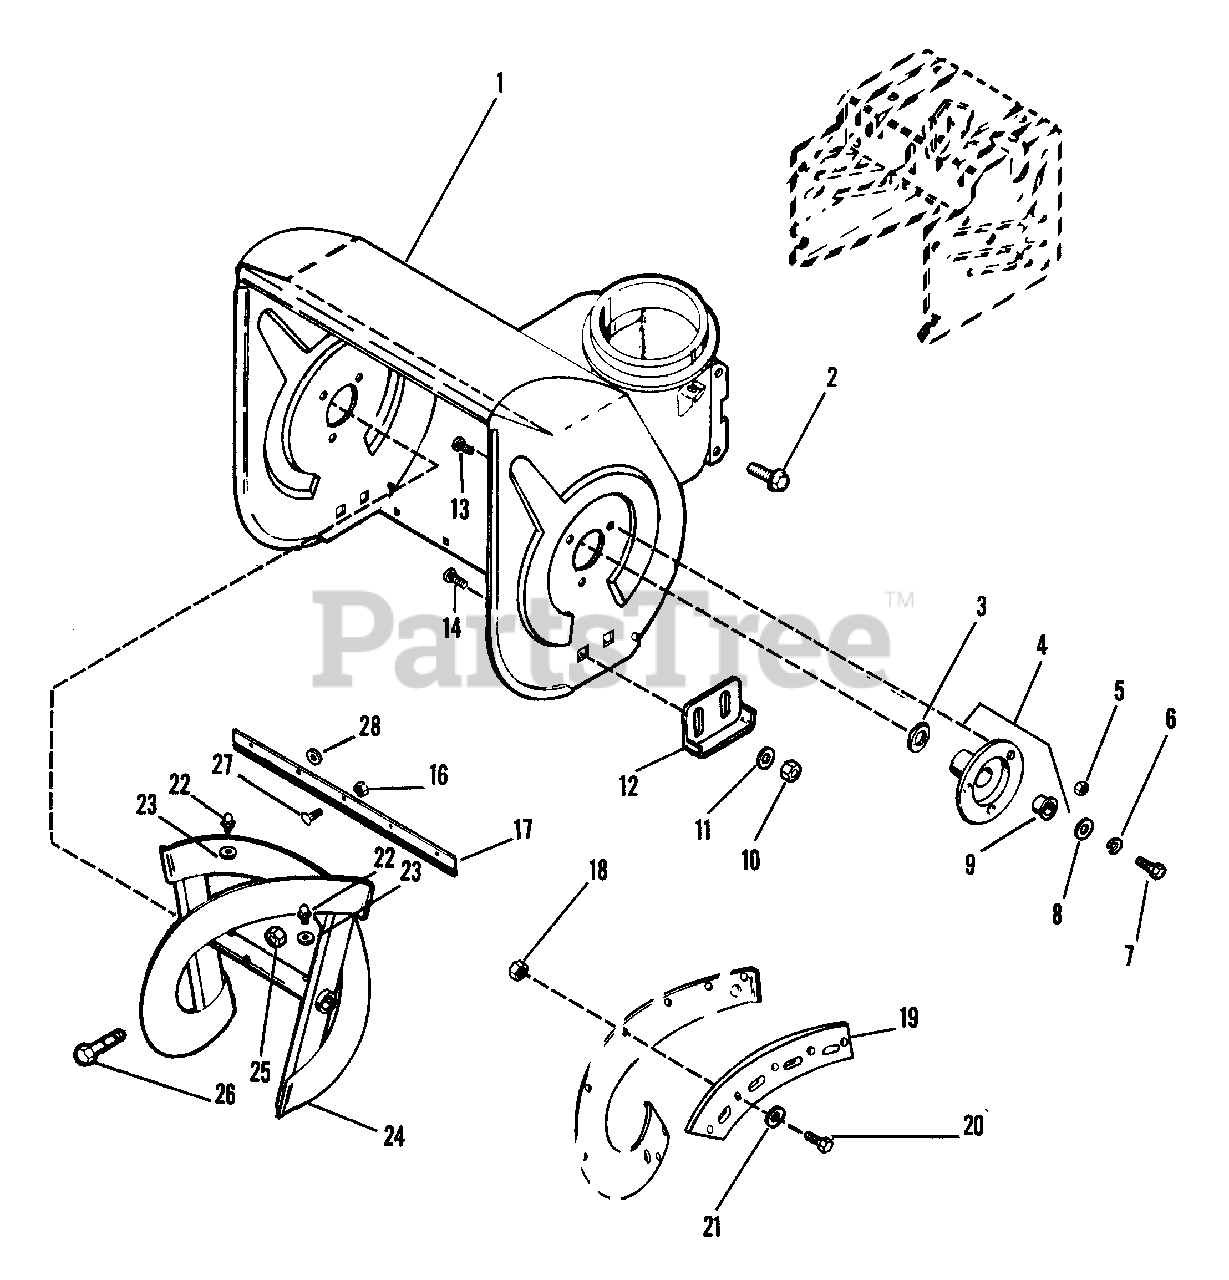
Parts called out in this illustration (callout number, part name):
1	20 IN BLOWER HOUSING WITH DECA
1	24 IN BLOWER HOUSING WITH DECA
1	AUGER/IMPELLER HOUSING 20" ST2
1	AUGER/IMPELLER HOUSING 20"
1	AUGER/IMPELLER HOUSING 24"
2	BLT-SERHFWH .31-18X.50 PL
3	WSHR-FL-STL.812X1.500X.139
4	BEARING FLANGE ASSEMBLY
5	NUT-LK-FLG .250-20 PL
6	WSHR-LK .312X.097 PL HVY
7	BLT-HEX .31-18X.63 PL GR 2
8	WSHR-FL-STL .344X1.375X.075 PL
9	BSHG-FLG .750X1.000X.625X1.250
10	NUT-LK-CTR .375-16 GR A PL
11	WSHR-FL-STL .38X.875X.083 PL
12	RUNNER
13	BLT-SERNK SL .25-20X.50 PL
14	BLT-RDHDSQNK .38-16X.75 SHT PL
16	NUT-LK-FLG .250-20 PL
17	SCRAPER BLADE
17	SCRAPPER SUPPORT
18	NUT-LK TOP 10-24 PL
19	RAKE EDGE W/HARDWARE
19	RAKE EDGE W/FLIGHTING
20	SCR-MCH 10-24X.63 HEX PL
21	WSHR-FL-STL .194X.492X.047 PL
22	SPIN DRIVE ZERK FITTING
23	WSHR-FL-STL .265X.500X.087 PL
24	RAKE, RIGHT-20(.75ID X10.88OD)
24	RAKE, LEFT-20"(.75ID X10.88OD)
24	RAKE, RIGHT-24"(.75ID X 10.88)
24	RAKE, LEFT-24(.75ID X 10.88OD)
24	RAKE, RIGHT-20(.75ID X 10.5OD)
24	RAKE, LEFT-20"(.75ID X 10.5OD)
25	NUT-LK-CTR .250-20 PL
26	SHEAR BOLT WITH NUT
27	BLT-RDHDSQNK .25-20X.75 GR5PL
27	BLT-RDHDSQNK .25-20X.50 SHT PL
28	WSHR-FL-STL .328X1.0X.094 PL
